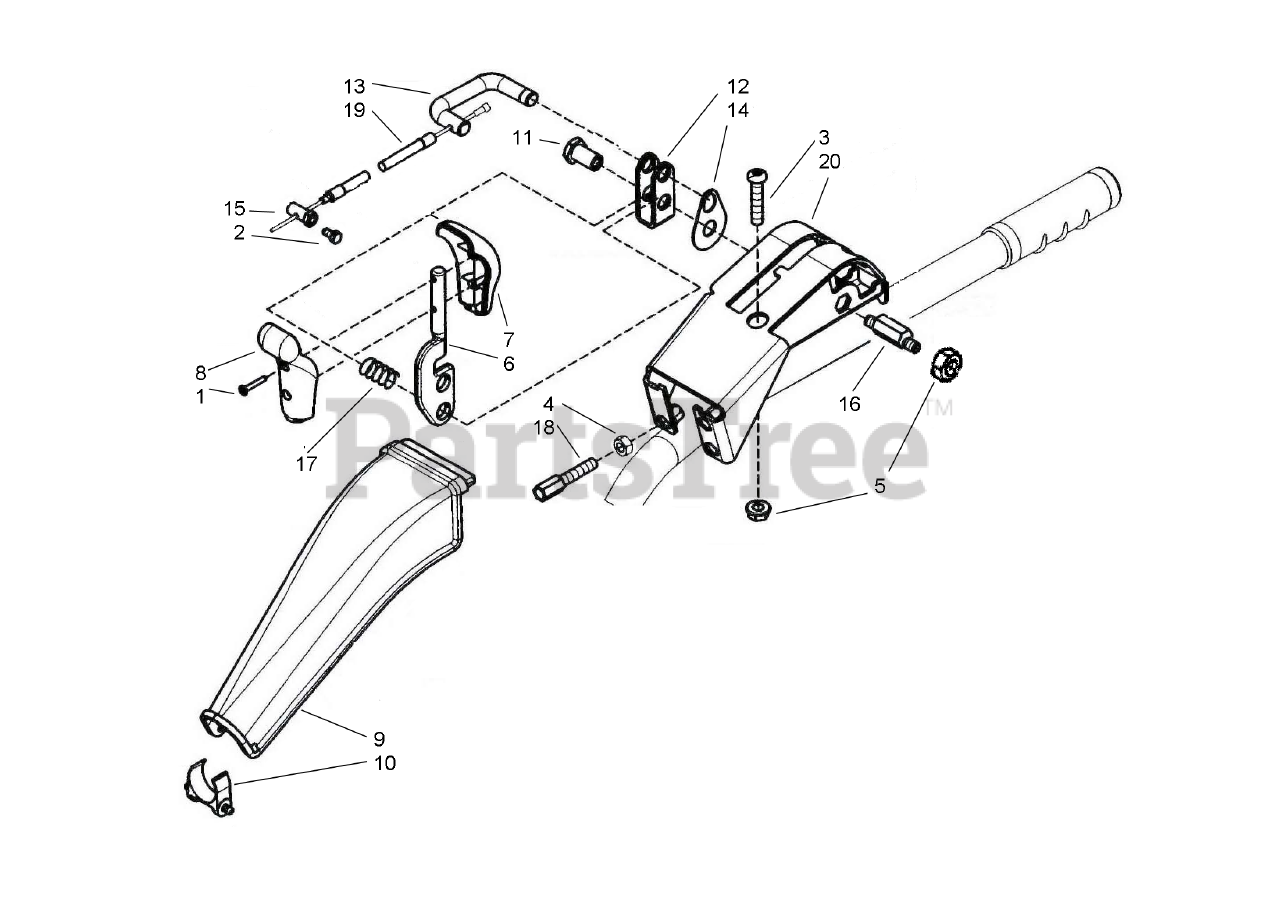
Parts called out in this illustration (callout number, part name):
1	SCREW 5X26
2	CAP SCREW, M6X16
3	SCREW
7	UPPER HANDLE HALF, RED
8	LOWER HANDLE HALF, RED
9	COVER
10	CROSS PIECE
11	BUSHING, REVERSE LEVER
13	ANCHOR
14	PLATE, SMALL
15	SCREW, CLAMPING
17	SPRING
18	ADJUSTER
19	CABLE & SHEATH
20	SUPPORT
